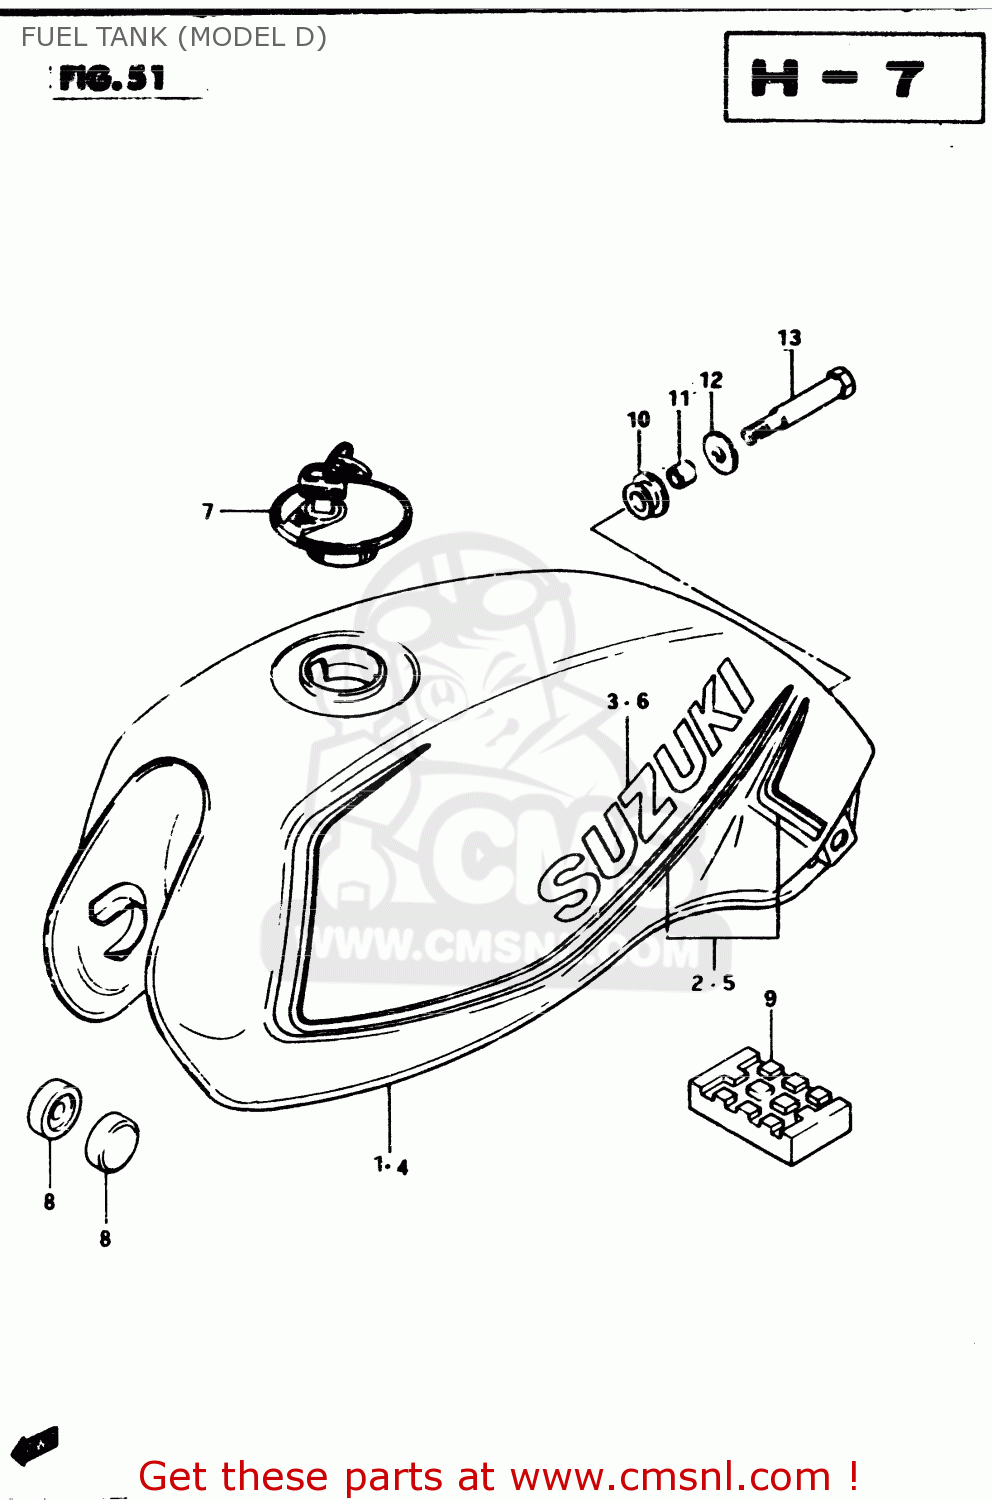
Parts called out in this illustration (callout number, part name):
1	TANK SET, FUEL (RED)
2	TAPE SET, FUEL TANK
3	EMBLEM(SILVER)
4	TANK SET, FUEL (SILVER)
5	TAPE SET, FUEL TANK
6	EMBLEM(ORANGE)
7	CAP SET,FUEL TANK
8	CUSHION
9	CUSHION,FUEL TANK CTR
10	CUSHION
11	SPACER (6.8X10X10)
12	WASHER (6.5X29X1.6)
13	BOLT(6X60)
